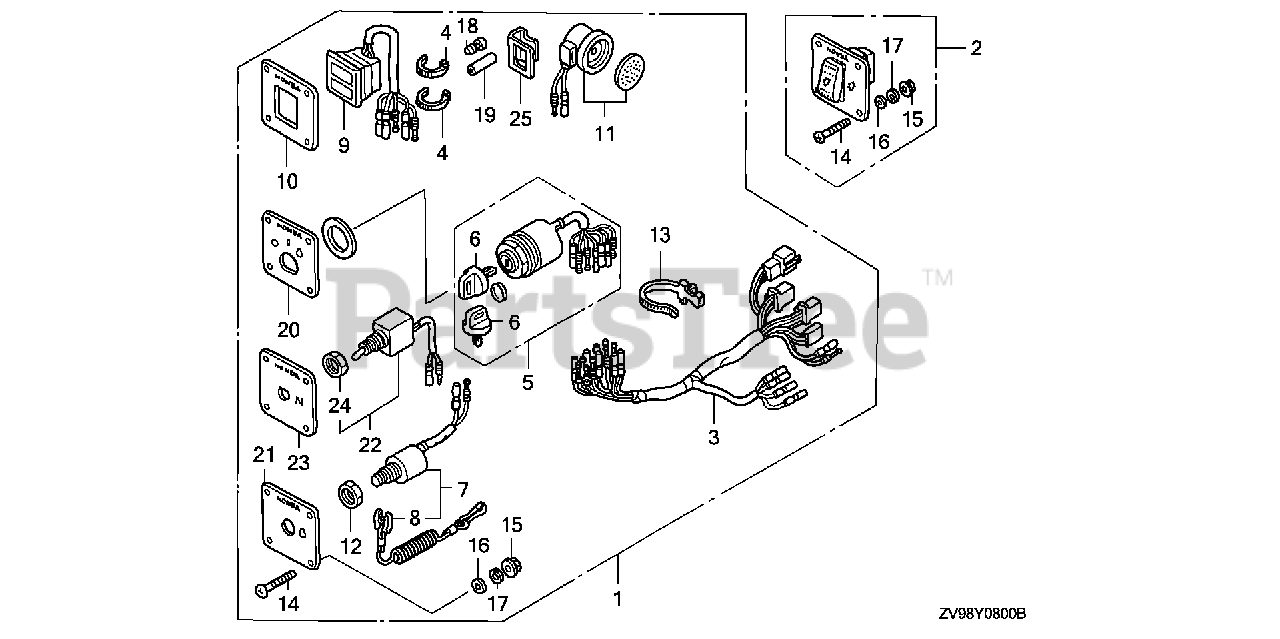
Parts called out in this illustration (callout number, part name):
1	PANEL KIT, CONTROL (B)
3	HARNESS ASSY., SWITCH PANEL
4	TIE, CABLE (2.4X92) (NATURAL)
5	SWITCH ASSY., COMBINATION
6	KEY ASSY., COMBINATION SWITCH (35100-ZV5-003 ONLY)
7	SWITCH ASSY., EMERGENCY STOP
8	WIRE, EMERGENCY
9	LAMP ASSY., INDICATOR (2-LED)
10	PANEL, INDICATOR
11	BUZZER, WARNING
12	NUT, HEX. (16MM)
13	BAND, WIRE HARNESS (150MM) (NATURAL)
14	SCREW, PAN (5X40)
15	NUT, FLANGE (5MM)
16	WASHER, PLAIN (5MM)
17	WASHER, SPRING (5MM)
18	PLUG, CONNECTOR (INNER)
19	PLUG, CONNECTOR (OUTER)
20	PANEL, SWITCH
21	PANEL, EMERGENCY STOP SWITCH
22	SWITCH ASSY., SOLENOID
23	PANEL, SOLENOID
24	NUT, HEX. (12MM)
25	BRACKET, BUZZER
